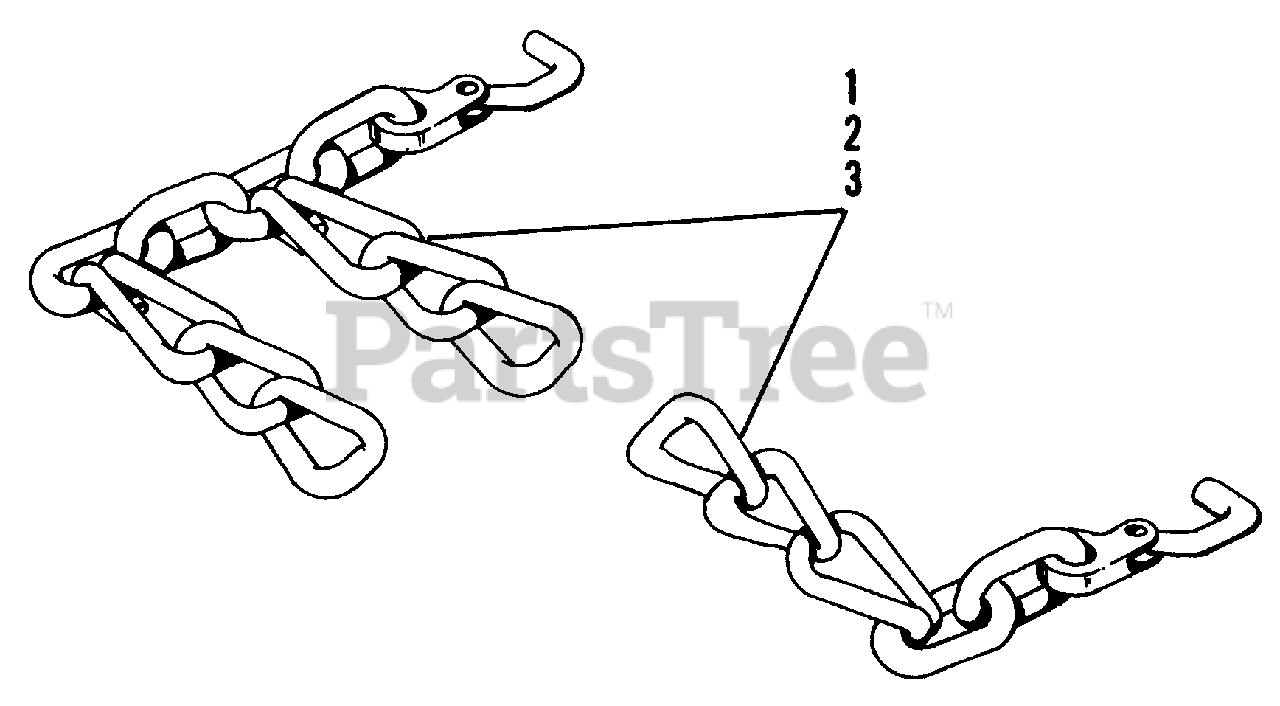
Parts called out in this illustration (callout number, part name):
1	Tire Chain (Mfg. No. 732)
2	Tire Chain (Mfg. No. 733)
3	Tire Chain (Mfg. No. 734)
